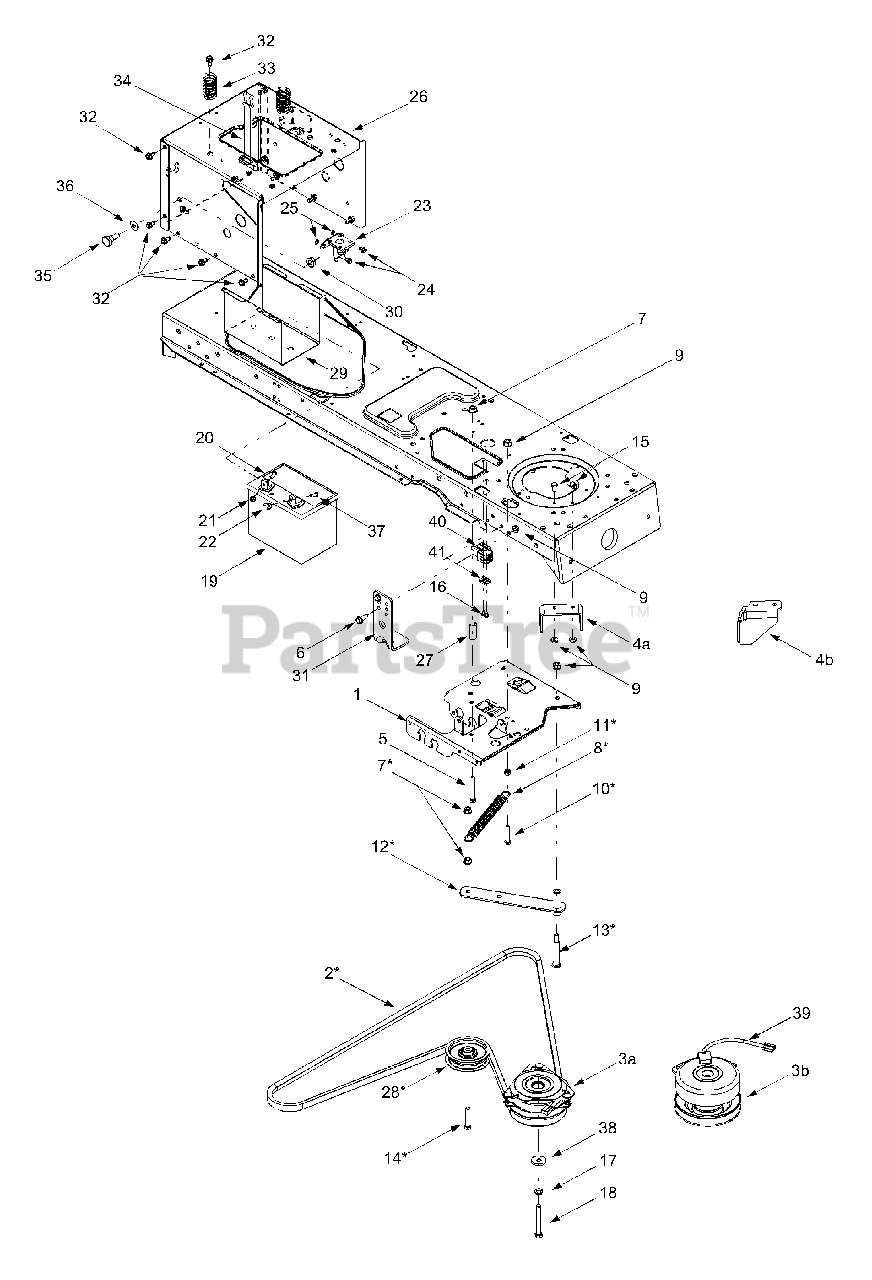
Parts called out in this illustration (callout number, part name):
2	PTO Belt
3A	Electric PTO Clutch (Model GT-2150)
3B	Electric PTO Clutch (Model GT-2550)
3B	Washer, Flat, 1.031 x 1.620 x .095
6	Hex Head Washer Screw, 5/16-18 x .875
7	Flange Lock Nut, 3/8-16
8	Extension Spring, .62 x 5.62
9	Flange Lock Nut, 5/16-18
10	Hex Cap Screw, 5/16-18 x 1.75
11	Hex Nut, 5/16-18
14	Hex Cap Screw, 3/8-16 x 2.0
15	Hex Cap Screw, 5/16-18 x .625
16	Screw, #10-16 x .5
17	Lock Washer, 7/16
18	Hex Cap Screw, 7/16-20 x 3.25 (Model GT-2150)
18	Hex Cap Screw, 7/16-20 x 2.50 (Model GT-2550)
19	12-volt Battery, 270 CCA
20	Hex Cap Screw, 1/4-20 x .62
21	Hex Sems Nut, 1/4-20
22	Wing Nut, 1/4-20
23	Solenoid, 12-Volt, 100 Amp
24	Self Tapping Screw, 1/4-20 x .5
25	Lock Washer, 1/4
28	Idler Pulley, 3.5
32	Self Tapping Screw, 5/16-18 x .625
33	Compression Spring, 1.28 x 3.125
34	Battery Strap
35	Shoulder Screw, .625 x .5, 7/16-20
36	Bell Washer, .45 x 1.0 x .062
37	Shoulder Screw, 1/4-20, .25 x .15
38	Flat Washer, .45 x 1.25 x .164
39	Harness Assembly, Electric PTO Clutch
40	Switch
41	Switch Plate
